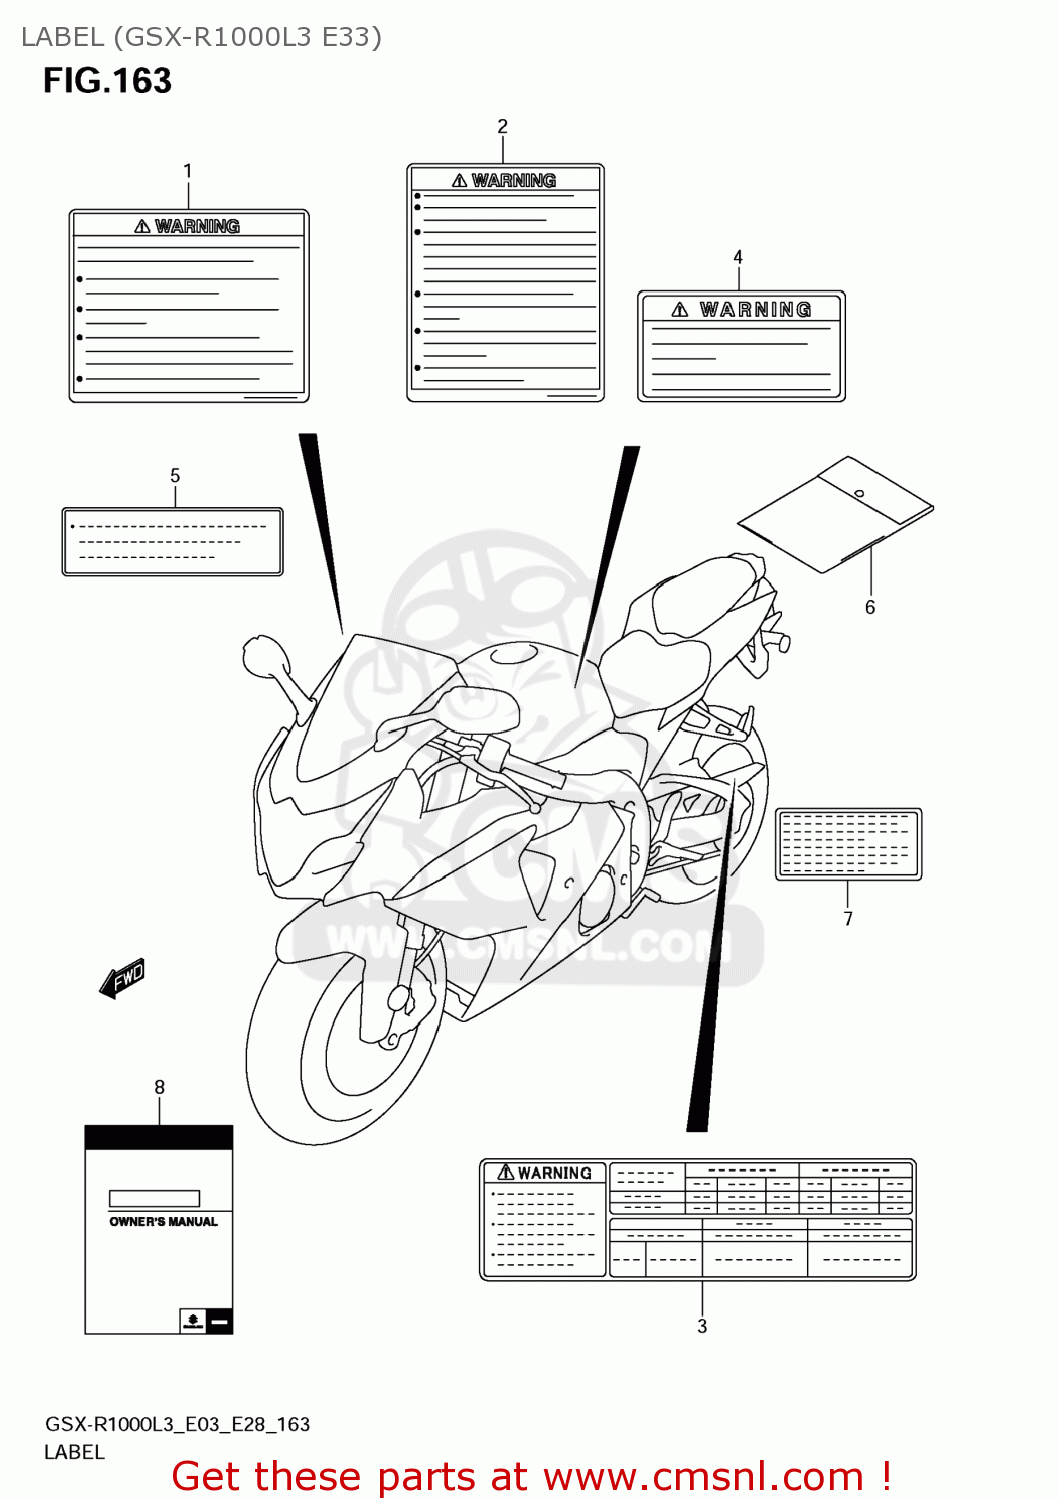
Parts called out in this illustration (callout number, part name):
1	LABEL,GENERAL WARNING
2	LABEL,SCREEN
3	LABEL,TIRE INFORMATION
4	LABEL,WARNING STEERING
5	LABEL,FUEL INFORMATION
6	BAG,OWNER'S MANUAL
7	LABEL,MANUAL NOTICE
8	MANUAL,OWNER'S
